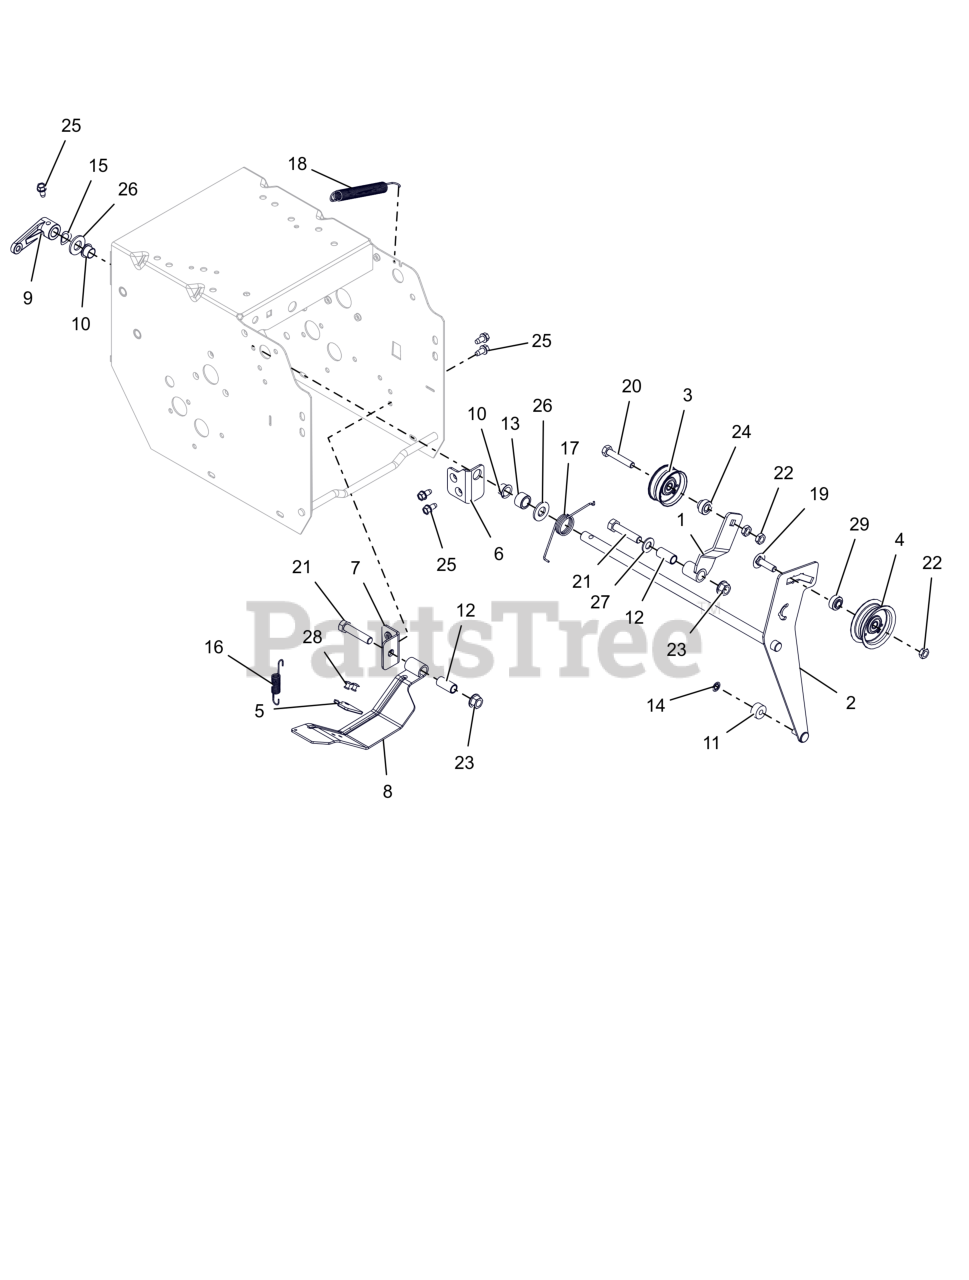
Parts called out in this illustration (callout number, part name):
1	WELDMENT, TRACTION IDLER ARM
2	WELDMENT- ATTACHMENT IDLER ARM
3	IDLER, FLAT - 1.875"
4	IDLER, FLAT - 2.00"
5	PAD, BRAKE
6	BRACKET, MOUNT - IDLER ARM
7	BRACKET, MOUNT - BRAKE
8	BRAKE ARM W/PAD
9	ARM, CLUTCH - ATTACHMENT
10	BUSHING, POLYLINER-.50 SPLIT
11	BSHG,SLV .265 X .625 X .375
12	BSHG-SLV .385X.500X1.045
13	BSHG-SLV .510X.751X.475
14	RG-RTNG-EXT .250X.010
15	WSHR-WAVE .50X.75X.015 .13FRHT
16	SPRING-EXT .437 X .438 X 2.64
17	SG-TORS .075 X .955
18	SPRING, EXTENSION
19	BLT, RHSSN .31-18X1.125 G5 ZCC
20	BLT, HEX .31-18X1.75 G5 ZCC
21	BLT, HEX .38-16X1.75 G5 ZCC
22	NUT-LK-CTR-JAM .312-18 GB ZCC
23	NUT-LK-TOP-FLG .38-16 ZC120
24	SPCR, BRG .315X.500X.481X.281
25	SCR-TAP .25-20X.50 HWH ZCC
26	WSHR,FLT .531X1.062X.095 ZCC
27	WSHR,FLT .406X.812X.065 ZCC
28	RVT, POP .1875 ZCC
29	SPCR, BRG .315X.500X.358X.281
